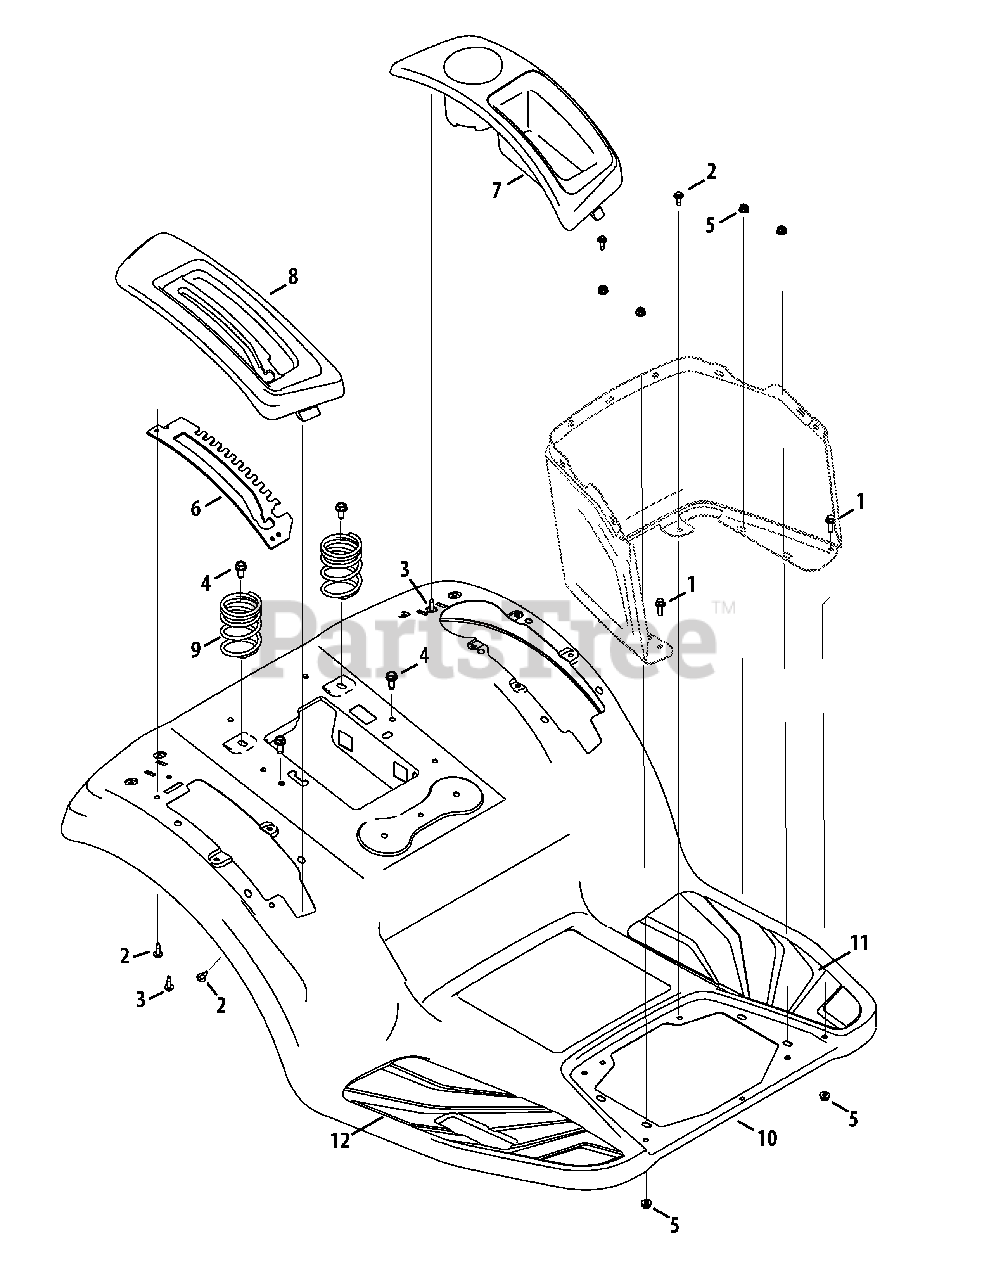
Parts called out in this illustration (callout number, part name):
1	Hex flange Screw, 1/4-20 x .75
2	Screw, M6-1 x .625
3	Screw, 1/4-10 x .75
4	Screw, Self-tapping, 3/8-16, 0.750,
5	Nut, Flange Lock, 1/4-20, Nylon
7	Cover, LH
8	Cover, RH, Manual PTO
9	Compression Spring, 2.50 x 3.951 x .207
10	Fender
11	Pad, Foot, LH
12	Pad, Foot, RH
